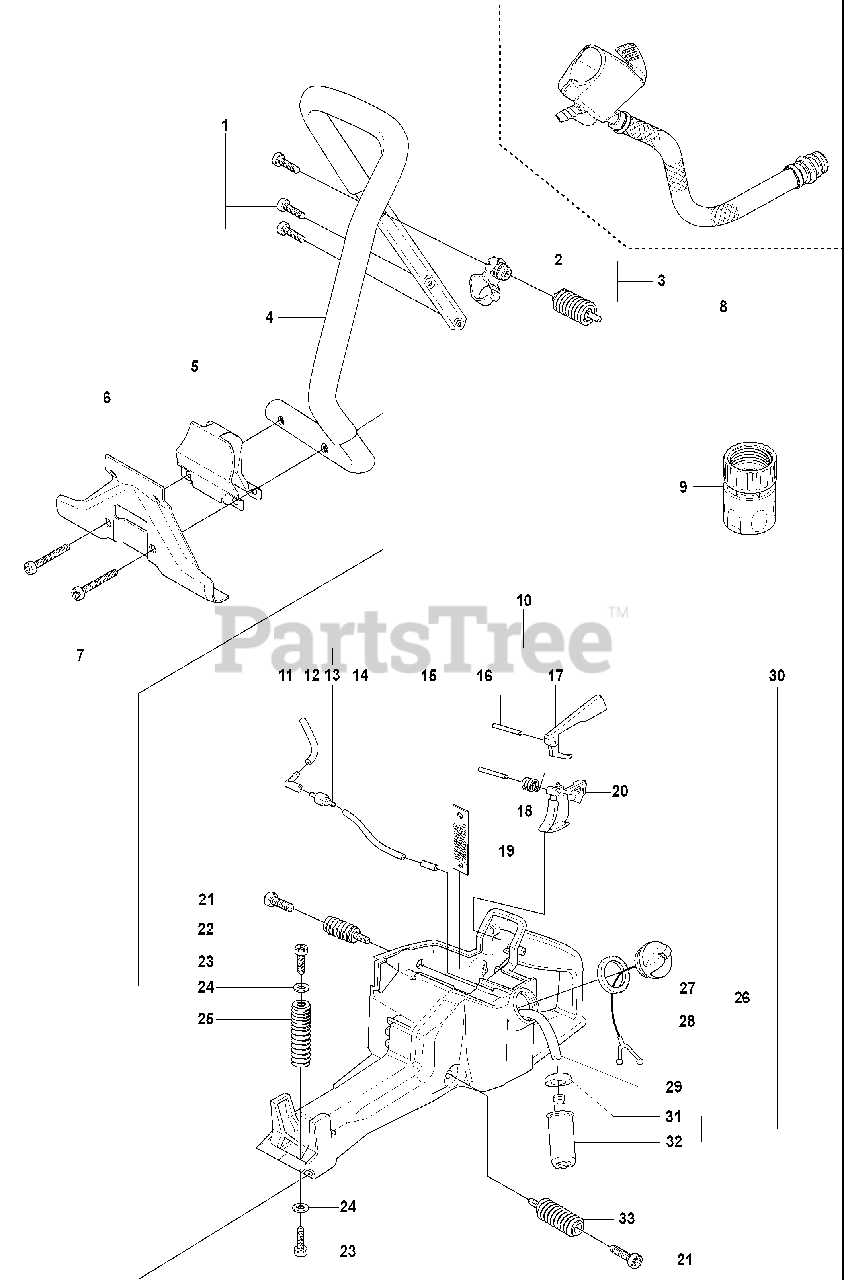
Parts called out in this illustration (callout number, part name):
2	SPRING RETAINER
3	VIB.INSULATOR
5	PROTECTIVE PLATE
6	GROUND SUPPORT
8	HOSE
9	COUPLER
10	FUEL TANK
11	CONNECTION BEND
12	FUEL HOSE
14	FUEL HOSE
16	PARALLEL PIN
17	THROTTLE LOCKOUT
18	SPRING THROTTLE TRIG
20	THROTTLE TRIGGER
22	ANTIVIB ELEMENT
24	WASHER STEEL
25	ANTIVIB ELEMENT
26	TANK CAP ASSY
28	TANK CAP HOLDER
29	FUEL HOSE
30	FUEL FILTER
31	HOSE CLAMP
32	FUEL FILTER
